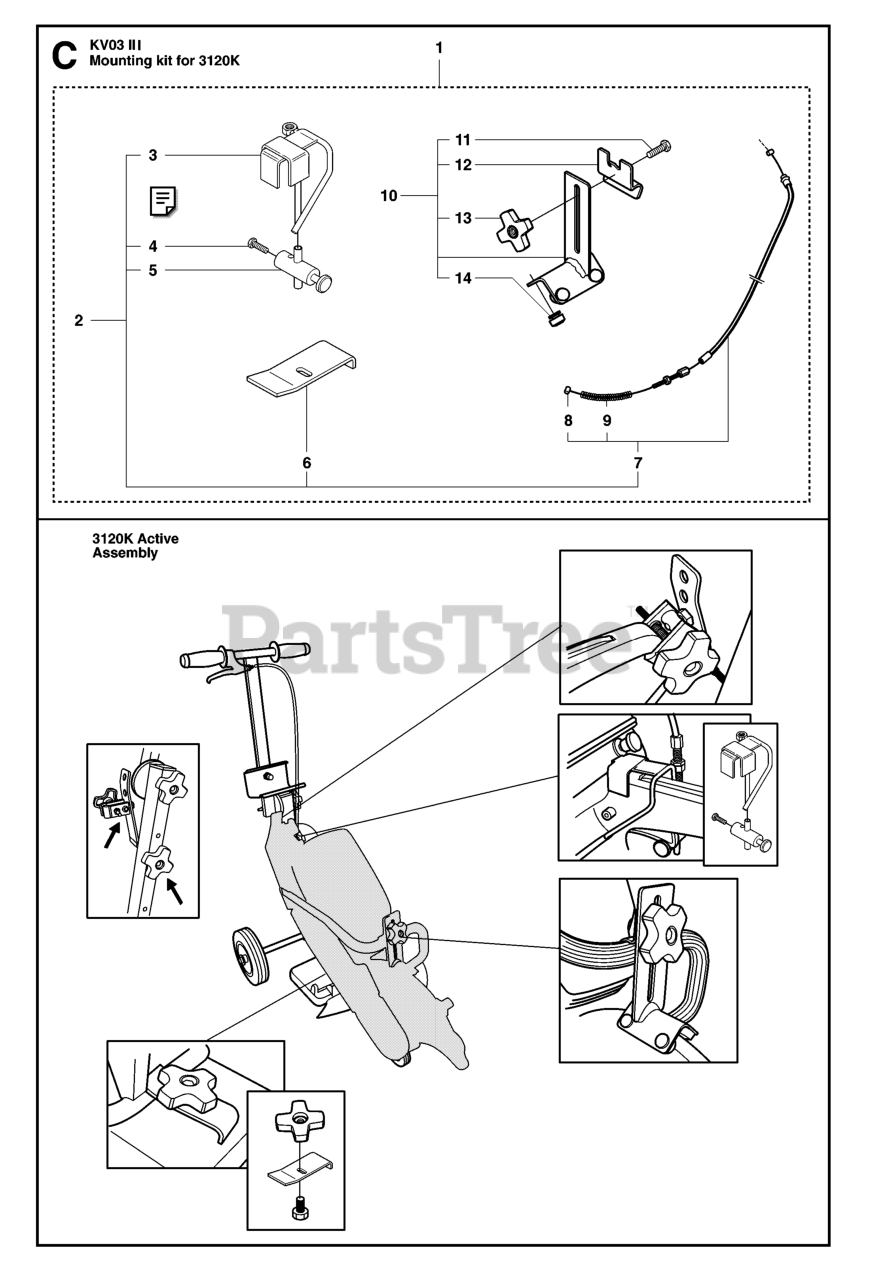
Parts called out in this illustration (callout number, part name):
1	ASSEMBLY KIT
2	KIT
4	Slotted Truss Head Screw #10-32 x 5/8"
7	CABLE ASSY.
8	Cable Retainer
11	SCREW 8X20
